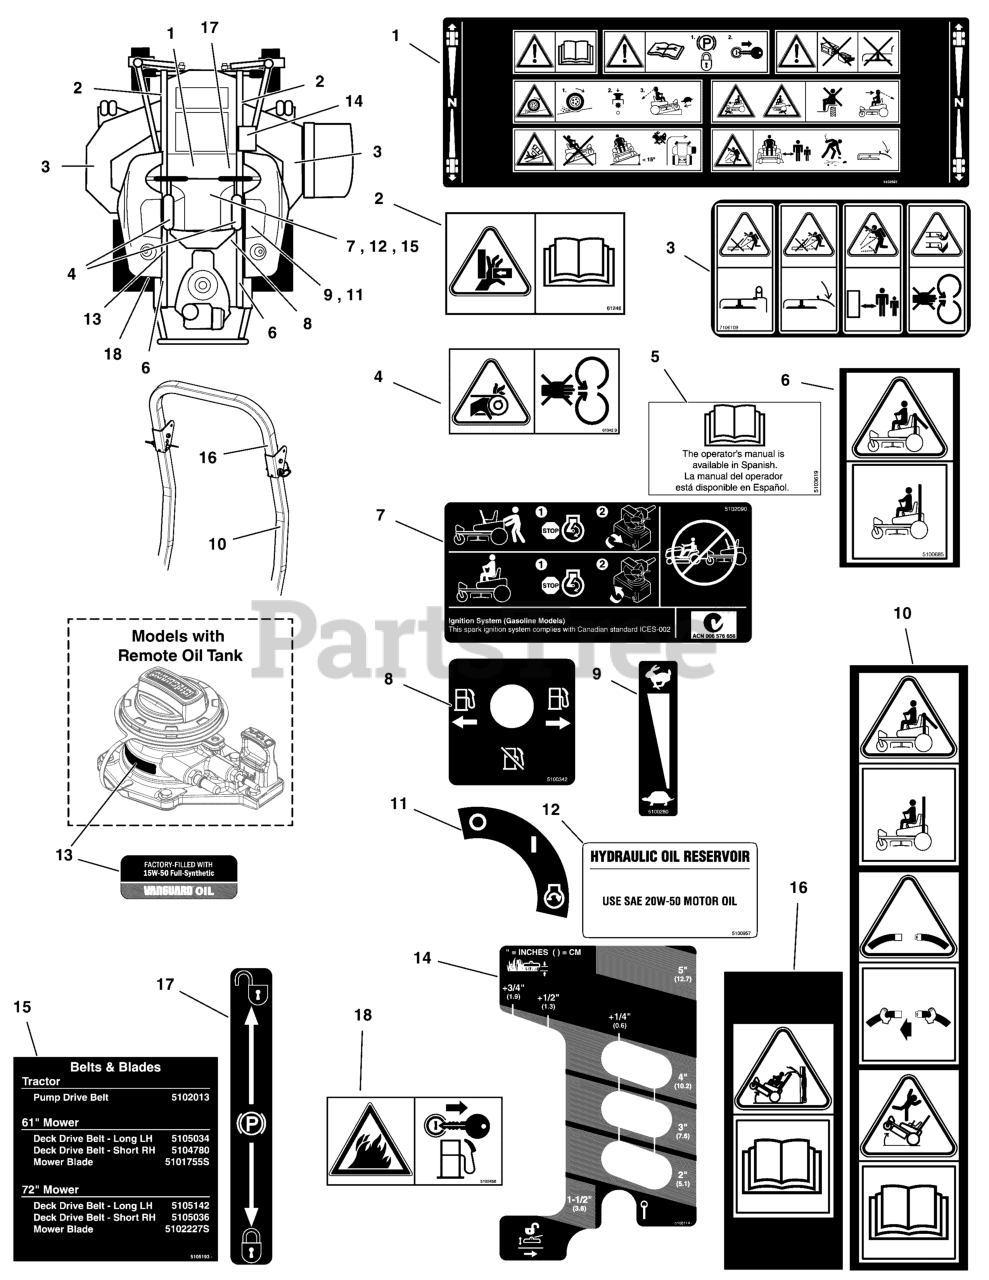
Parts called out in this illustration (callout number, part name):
1	DECAL, MAIN SAFETY, EXPORT
2	DECAL, Pinch Point, CE
3	DECAL, DISCHARGE SAFETY, EXPORT
4	DECAL, CE DANGER, HAND IN BELT
5	DECAL, MANUAL AVAIL IN SPANISH
6	DECAL, WARNING, ROLL BAE, CE
7	DECAL, TRANSAXLE RELEASE, S200XT
8	DECAL, FUEL VALVE
9	DECAL, THROTTLE CONTROL
10	DECAL, SAFETY, CE ROPS (SV)
11	DECAL, IGNITION SWITCH
12	DECAL, HYDRAULIC OIL, 20W50
13	LABEL, OIL INFORMATION
14	DECAL-HEIGHT CITATION
15	DECAL, BELT & BLADE S200XT, F210Z, 2BELT
16	DECAL, SAFETY, CE ROPS, OBS (SV)
17	DECAL, PARKING BRAKE SYMBOLS
18	DECAL, FIRE ANSI EXPORT
